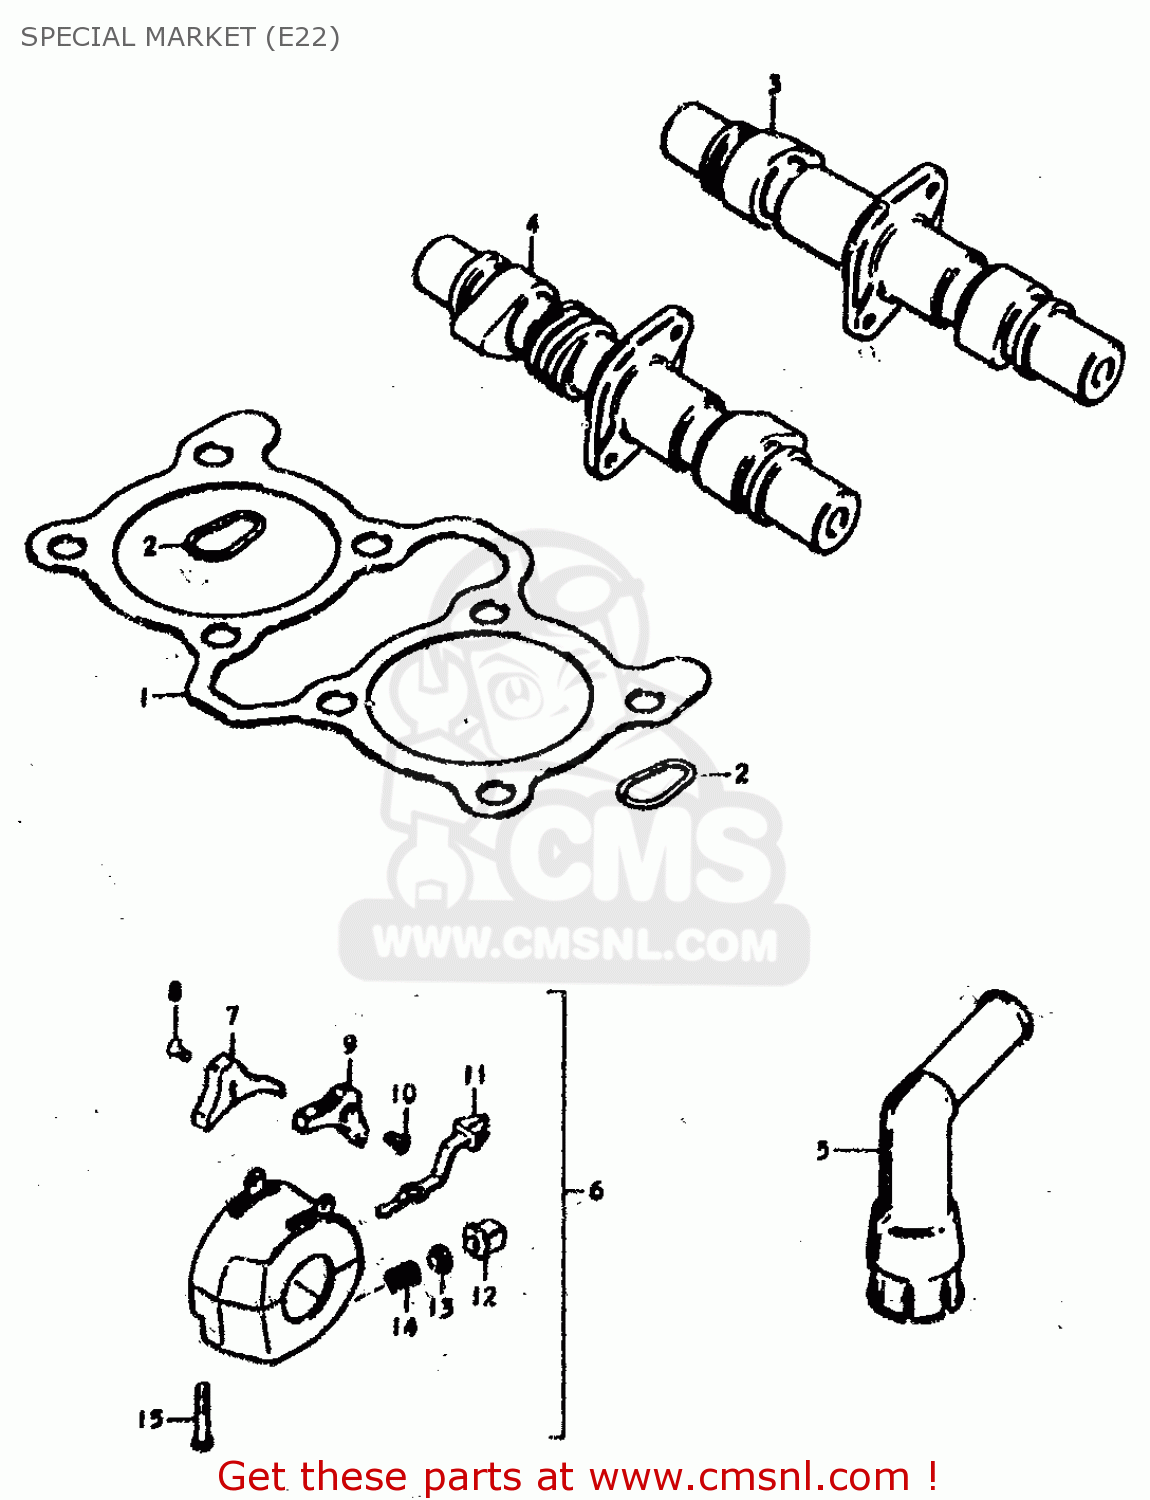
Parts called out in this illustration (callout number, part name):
1	GASKET,CYLINDER
2	O RING,CYLINDER NO.2
3	CAM SHAFT,INTAKE
4	CAM SHAFT,EXHAUST
5	CAP, SPARK PLUG (S)
6	SWITCH ASSY,HANDLE LH
7	KNOB,LIGHTING SWITCH
8	SCREW
9	KNOB,DIMMER SWITCH
10	SCREW
11	KNOB,TURNSIGNAL
12	BUTTON,HORN
13	CONTACT
14	SPRING
15	SCREW
